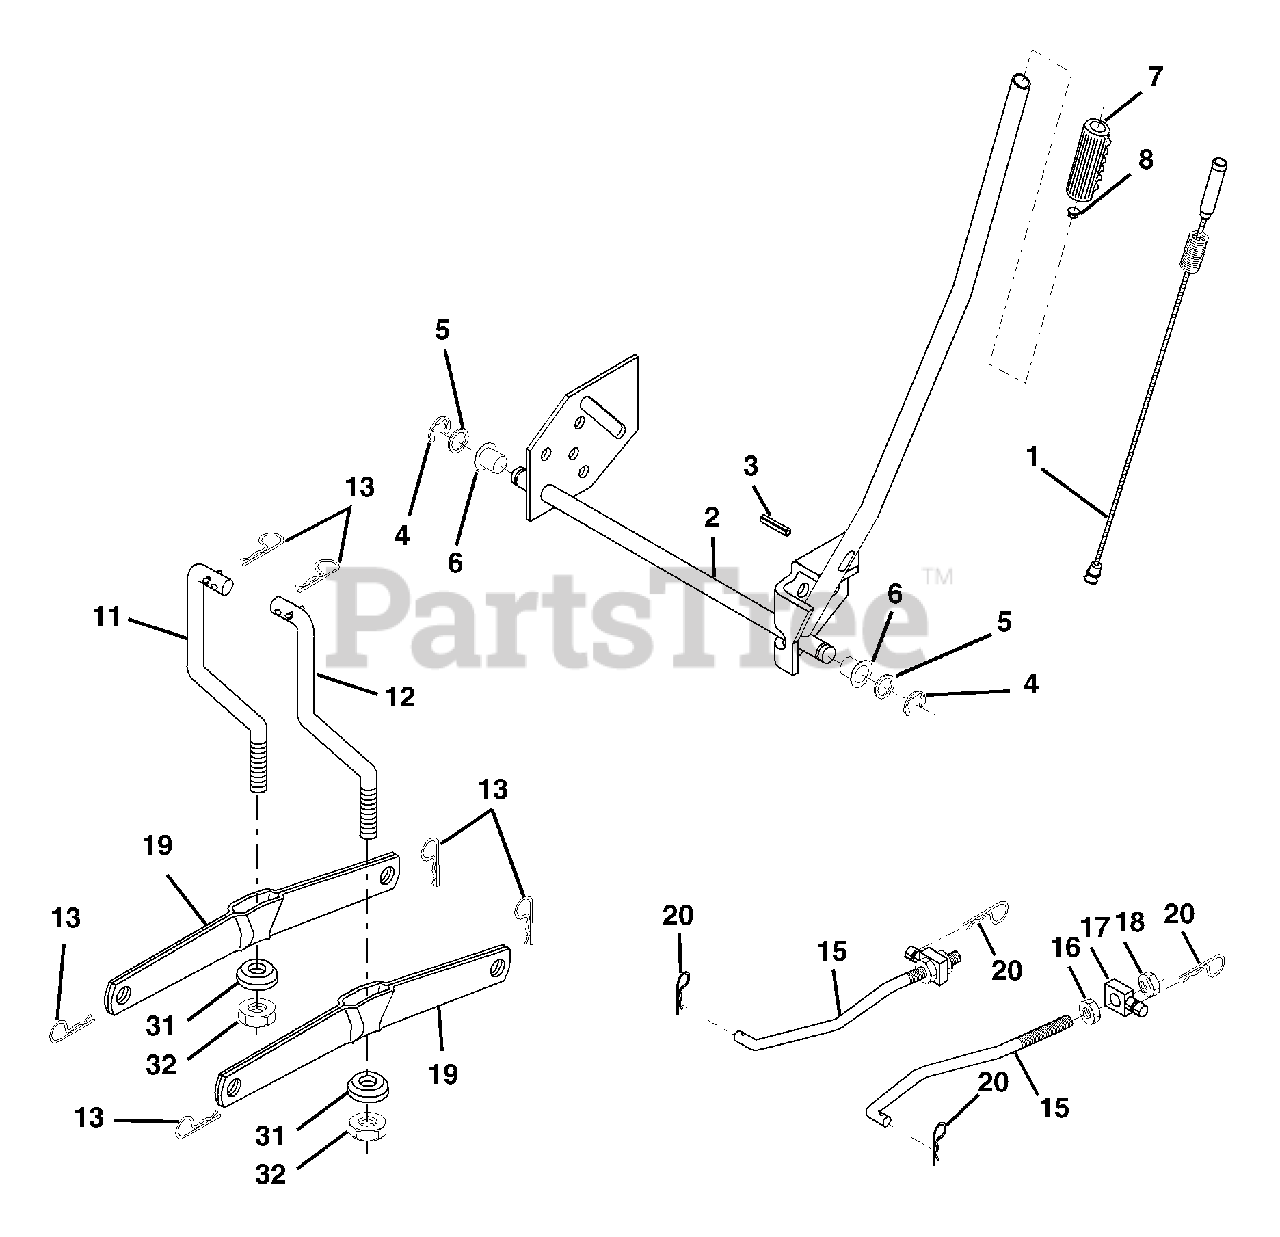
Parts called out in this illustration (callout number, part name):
1	Wire Asm Inner/Sprg W/plunger
2	Shaft Asm Lift RH w/Inf
3	Pin Groove 2"
4	E Ring #5133-62
5	Washer 21/32 x 1 x 21 Ga.
6	Bearing Nylon Blk 629 Id
7	Grip Handle
8	Button Plunger
11	Link Lift LH Fixed Length
12	Link Lift RH Fixed Length
13	Retainer Spring
15	Link Front
16	Nut Jam Hex 1/2-13 unc
17	Trunnion
18	Nut Lock W/Wsh 1/2-13 unc
19	Arm Suspension Rear
20	Retainer Spring
31	Bearing Pvt Lift
32	Nut Crownlock 3/8 - 24
